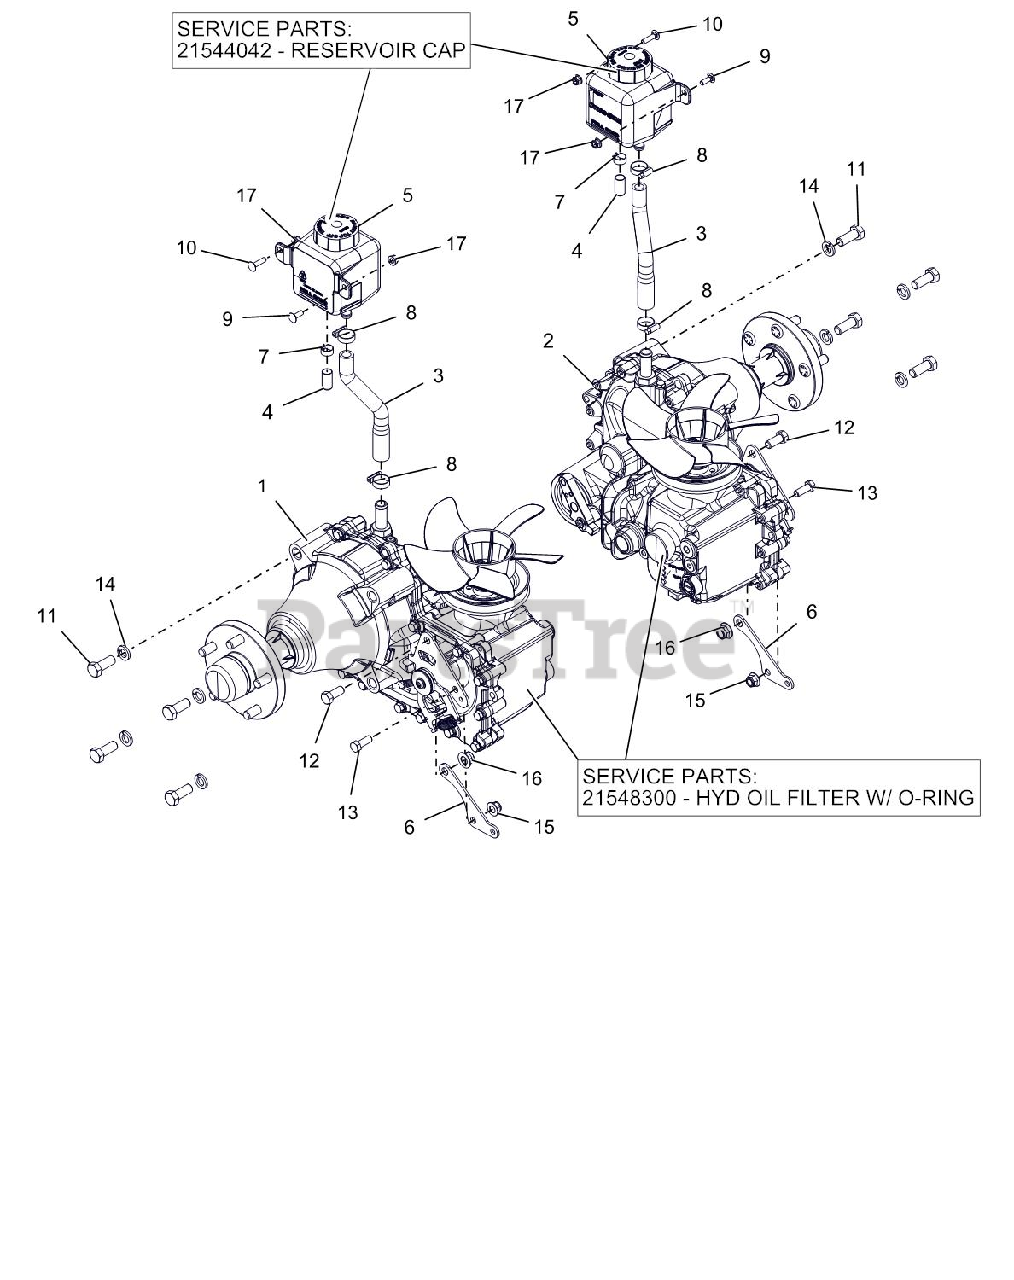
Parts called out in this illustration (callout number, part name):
1	TRANS, RH HG ZT-5400
2	TRANS, LH HG ZT-5400
3	HOSE,PT200/400 TRANS OVERFLOW
4	CAP, .50 BARBED FITTING
5	CAP, HYDRO RESERVOIR REPLAC.
5	TANK, HYDRO OVERFLOW 700 ML
6	DRV CNTRL LINKAGE MTG BRKT-BLK
7	CLAMP, .62 SPRING
8	CLAMP,.88 DIA. HOSE
9	@BLT-RDHDSQNK .25-20X.75 G5YZ
10	@BLT-RDHDSQNK .25-20X1.00 G5YZ
11	@BLT-HEX .50-13X1.25 GR5 YWZC
12	@BLT-HEX .44-14X1.00 GR5 YWZC
13	@BLT-HEX .38-16X1.00 GR5 YWZC
14	@WSHR-LK .50X.125 REG YWZC
15	@NUT-LK-NYL-FLG .38-16 YWZC
16	@NUT-LK-NYL-FLG .44-14 YWZC
17	@NUT-LK-NYL-FLG .25-20 YWZC
18	FILTER,HYD OIL W/ORING ZT-54OO
